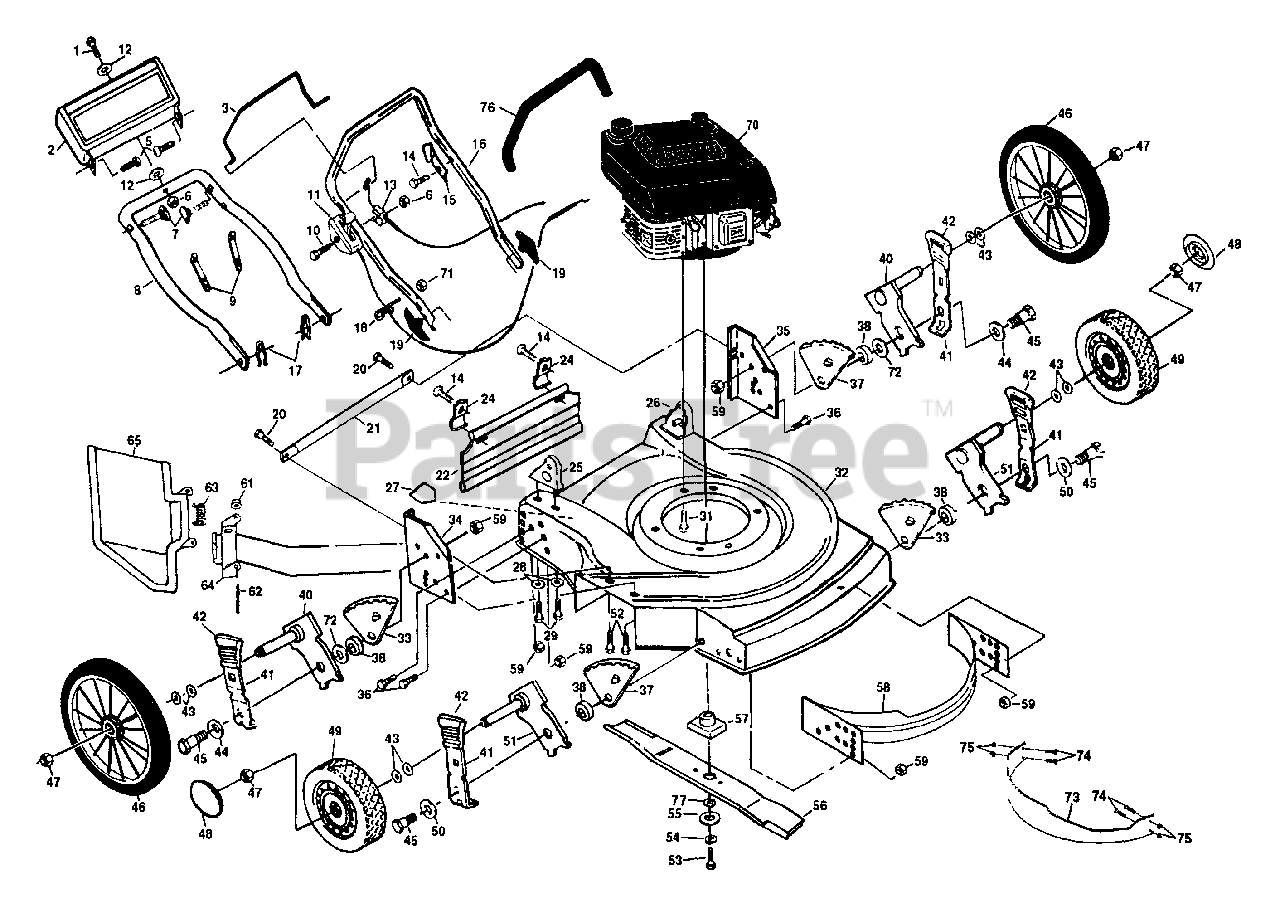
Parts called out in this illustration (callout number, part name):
1	Hex Head Washer Screw 1/4-20 x 1-1/2
2	Trim Plate
3	Control Bar
5	Self-tapping Screw #10-24 x 5/8
6	Locknut 1 /4-20
7	Handle Bolt 5/16-18 x 1-3/4
8	Lower Handle
9	Wire Tie
10	Machine Screw 1/4-20 x 2-1/4
11	Throttle Control
13	Engine Zone Control Cable
14	Hex Washer Head Screw #10-24 x 1/2
15	Up-Stop Bracket
16	Upper Handle
17	Hairpin Cotter
18	Rope Guide
19	Handle Knob
20	Self-tapping Screw 1/4-20 x 1/2
21	Support Rod
22	Rear Skirt
24	Skirt Bracket
25	Handle Bracket Assembly (Right)
26	Handle Bracket Assembly (Left)
27	Danger Decal
29	Thread Cutting Screw 5/16-18 x 1-3/4
31	Thread Rolling Screw 3/8-16 x 1
32	Lawn Mower Housing
33	Wheel Adjusting Bracket (LF/RR)
34	Wheel Support Bracket (Right)
35	Wheel Support Bracket (Left)
36	Hex Head Bolt 3/8-16 x 3/4
37	Wheel Adjusting Bracket (RF/LR)
38	Spacer
40	Axle Arm Assembly (Rear)
41	Selector Spring
42	Selector Knob
43	Washer
44	Washer
45	Shoulder Bolt 3/8-16
46	Wheel & Tire Assembly 16.0 x 2.0
47	Locknut
49	Wheel & Tire Assembly 8.0 x 2.0
51	Axle Arm Assembly (Front)
52	Hex W/Sems 1/4-20 3/8 Screw
53	Hex Head Screw 3/8-24 x 1-3/8 Gr. 8
54	Helical Washer 3/8
55	Hardened Washer
57	Blade Adapter
58	Front Baffle & Rear
59	Locknut 3/8-16
62	Hinge Rod
63	Torsion Spring
64	Housing Bracket Assembly
65	Discharge Guard
69	Thread Rolling Screw #10-32 x 5/8
71	Keps Locknut 1 /4-20
72	Flat Washer 3/8
73	Mulcher Baffle
76	Foam Grip
77	Washer
